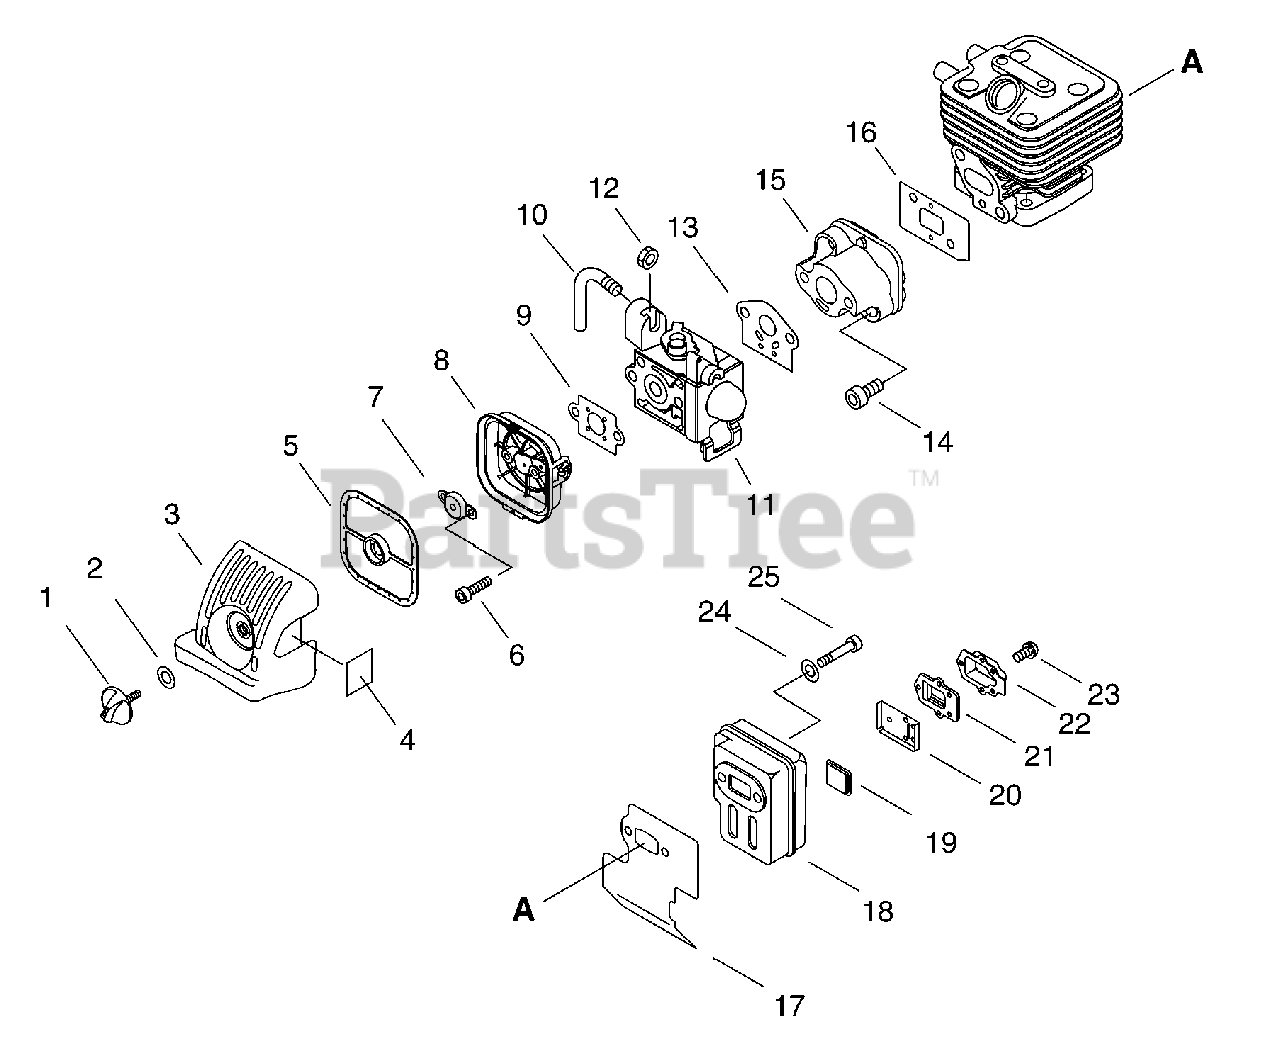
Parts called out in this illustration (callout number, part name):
1	KNOB, FASTENER
3	COVER, AIR FILTER
4	LABEL - CHOKE
5	FILTER, AIR
6	SCREW - 5X60
7	PLATE, PREVENT
8	CLEANER CASE ASSY
9	GASKET, INTAKE
10	CONNECTOR, CABLE
11	CARBURETOR
13	GASKET, INTAKE
14	SCREW - 5X25
15	INSULATOR, INTAKE
16	GASKET, INTAKE
17	GASKET, EXHAUST
18	MUFFLER
19	SCREEN, SPARK ARRESTOR
20	GASKET,EXHAUST
21	GUIDE, EXHAUST - INNER
22	GUIDE, EXHAUST - OUTER
23	SCREW - 4X10
24	WASHER - 5
25	SCREW - 5X55
